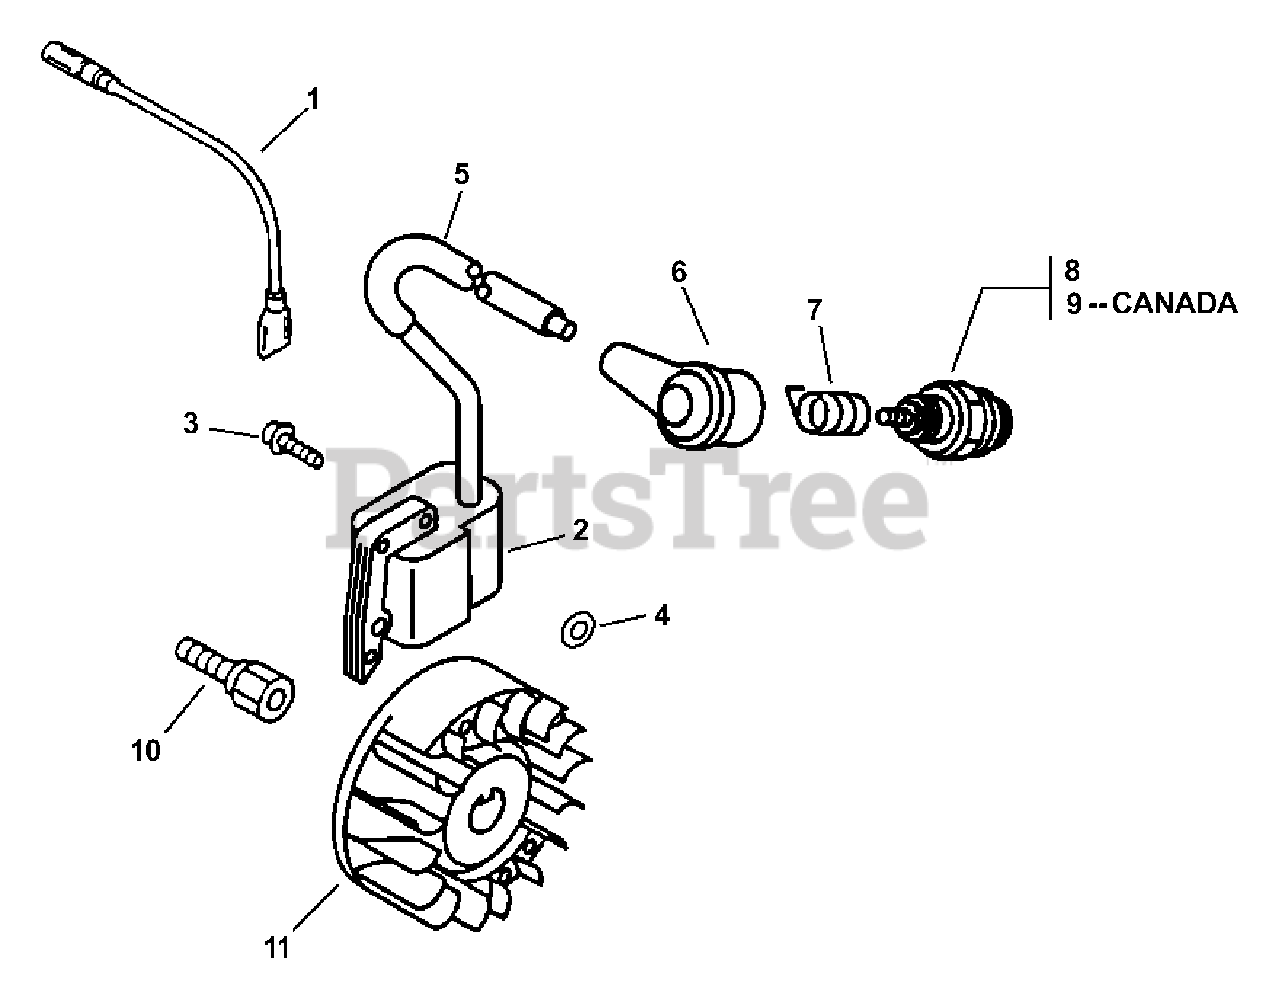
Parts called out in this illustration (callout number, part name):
1	LEAD - IGNITION
2	COIL, IGNITION
3	SCREW - 4X22
6	CAP, SPARK PLUG
7	TERMINAL, SPARK PLUG CAP
8	SPARK PLUG -- BPM-7Y
9	SPARK PLUG -- BPMR-7A
10	HUB, FAN
11	FLYWHEEL
